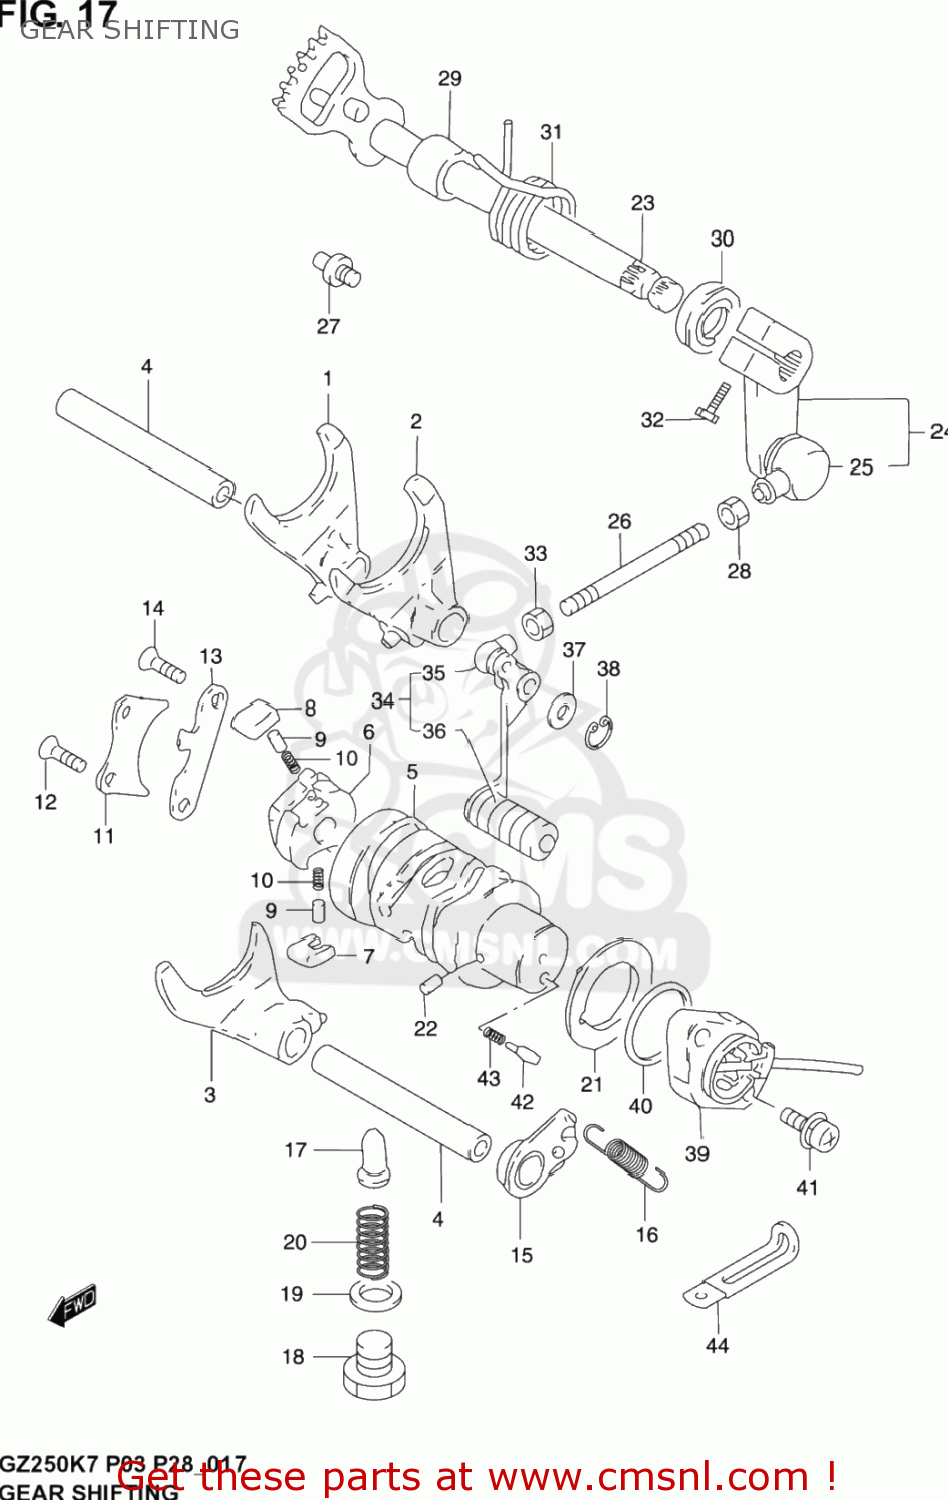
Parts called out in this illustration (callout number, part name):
1	FORK,GEAR SHIFT NO.1
2	FORK,GEAR SHIFT NO.2
3	FORK,GEAR SHIFT NO.3
4	SHAFT,GEAR SHIFT FORK
5	CAM,GEAR SHIFT
6	GEAR,GEAR SHIFT CAM DRIVEN
7	PAWL,GEAR SHIFT NO.1
8	PAWL,GEAR SHIFT NO.2
9	PIN(5X8)
10	SPRING
11	LIFTER,GEAR SHIFT POLE
12	SCREW
13	GUIDE,GEAR SHIFT CAM
14	SCREW
15	STOPPER,GEAR SHIFT CAM
16	SPRING
17	STOPPER,GEAR SHIFT CAM NO.2
18	PLUG (14X12)
19	GASKET(13.8X18.8X4.8) (NAS)
20	SPRING
21	PLATE,GEAR SHIFT CAM STOPPER
22	PIN
23	SHAFT,GEAR SHIFT
24	ARM,GEAR SHIFT LINK
25	COVER,DUST
26	ROD,GEAR SHIFT LINK
27	STOPPER,GEAR SHIFT ARM
28	NUT
29	SPACER(12X20X15.3)
30	OIL SEAL
31	SPRING
32	BOLT
33	NUT
34	LEVER ASSY,GEAR SHIFT
35	COVER,DUST
36	RUBBER,GEAR SHIFT PEDAL
37	WASHER(12.5X20X1)
38	CIRCLIP,12 MM
39	BASE ASSY,NEUTRAL SW TERMINAL
40	O RING(D:2.4,ID:26.2)
41	SCREW
42	PIN(5X15.5)
43	SPRING
44	CLAMP(L:45)
